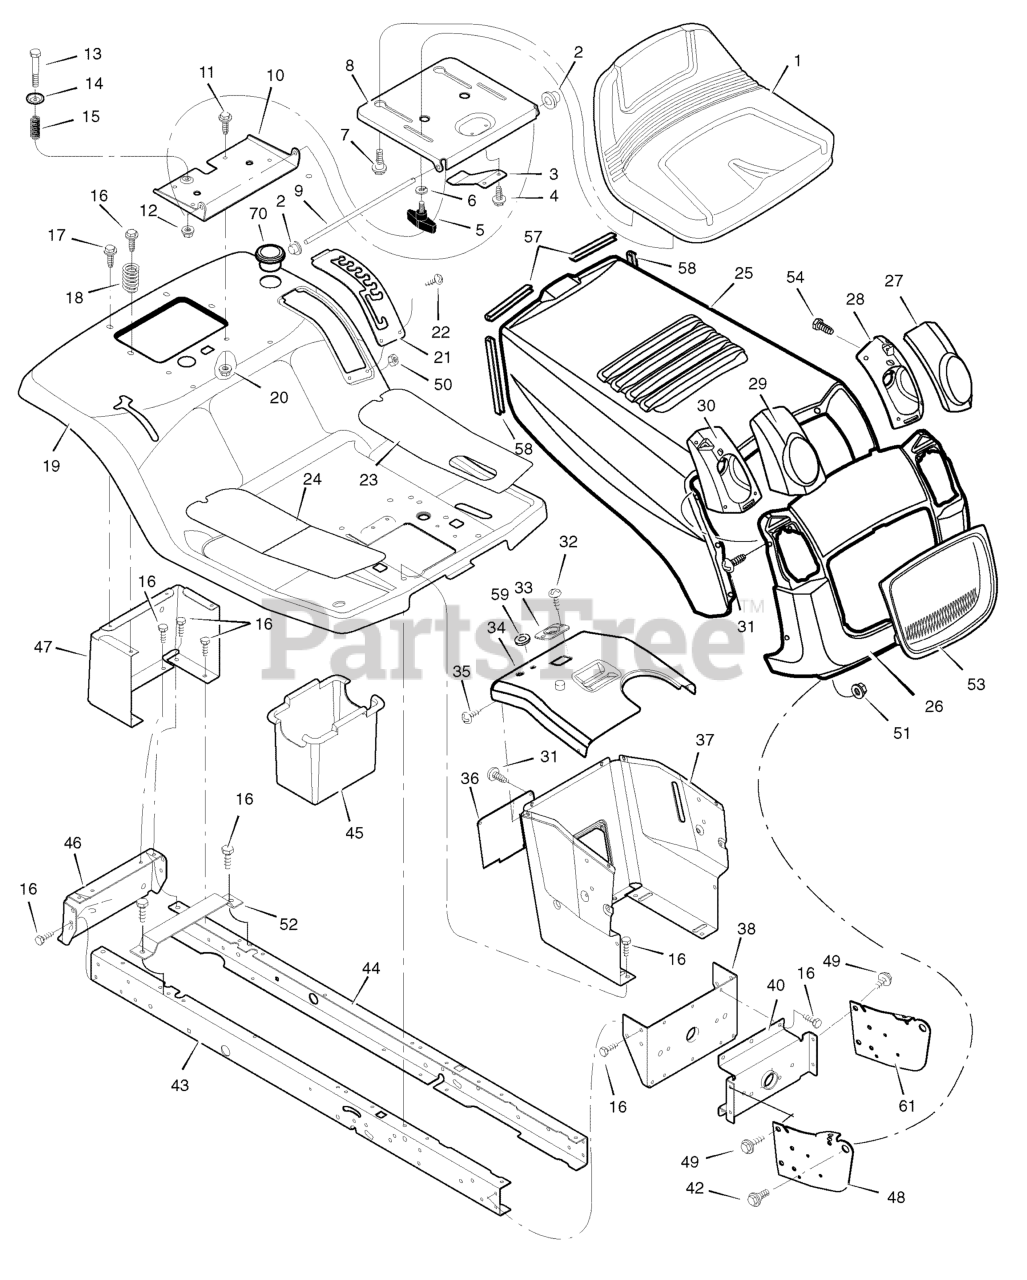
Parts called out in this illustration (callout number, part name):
2	CAP, Push On
5	BOLT, Wing
6	WASHER
7	BOLT, Shoulder
8	SUPPORT, Seat
9	ROD, Pivot
10	BRACKET, Seat Pivot
11	BOLT
13	BOLT, Shoulder
14	WASHER, Cup
19	DECK, Seat
20	NUT
21	PLATE, Lift
23	MAT, Left
24	MAT, Right
26	GRILLE, X1/X3
27	LENS, Left
28	HOUSING. Left Headlamp
29	LENS, Right
30	Housing, Right Headlamp
33	BEARING, Steering
36	PANEL, Access
37	SUPPORT, Dash
38	BRACKET, Rear Hanger
40	AXLE, Hanger
42	BOLT, Shoulder
43	FRAME, Right
44	FRAME, Left
45	Container, Battery
46	PLATE, Hitch
47	PANEL, Rear
48	SUPPORT, Right Grille
51	NUT
52	SUPPORT, Battery
53	INSERT, Grille
54	SCREW, Hex Head
57	TRIM, Hood (3.75")
58	TRIM, Hood (6.5")
59	GROMMET, Parking Brake
61	SUPPORT, Left Grille
70	HOLDER, Cup
